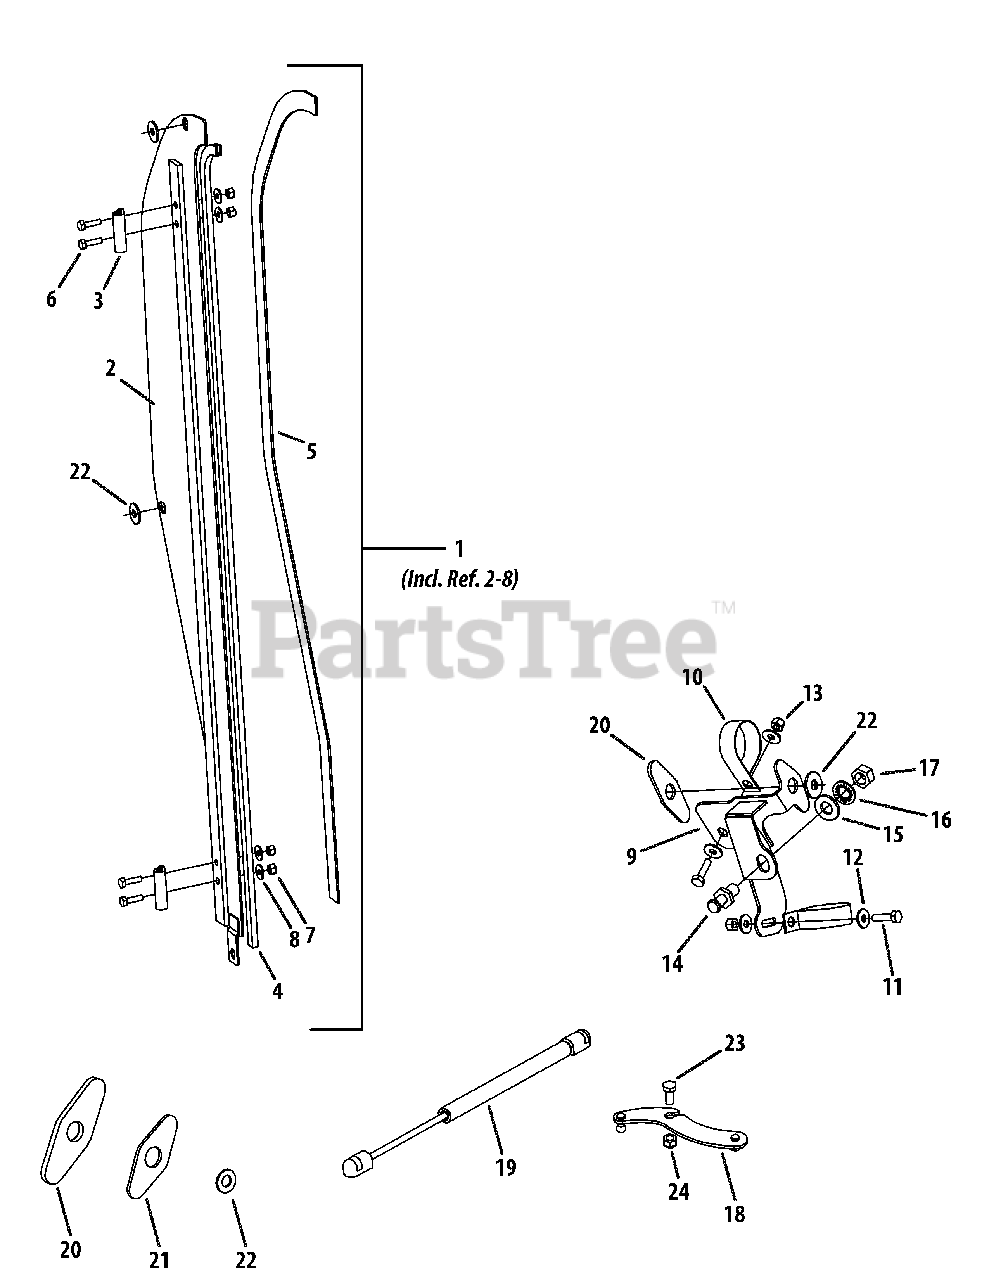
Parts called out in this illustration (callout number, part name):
1	Door Hng. Panel-R, (incl. Ref. 2-8)
2	Hinge Panel
3	Tube Frame Hinge, 10 Gauge
4	Standard Trim Lock, 1/8" Grip
5	Foam Seal, 1" X 1/8
6	Hex Bolt, 1/4-20 x 1"
7	Washer, 1/4"
8	Lock Nut, 1/4-20
9	Door Striker - R
10	Door Hardware Kit
11	Hex Bolt, 1/4-20 x 1"
12	Washer, 1/4"
13	Lock Nut, 1/4-20
14	Striker Bolt For Rotary Latch
15	Washer, 1/2"
16	Lock Washer, 1/2"
17	M10 Nut
18	Door Frame Spring Mount, RH
19	Gas Spring (12") W/Quick Release
20	Rubber Door Filler, ROPS
21	S/M 2.75 X 1.25 Door Washer
22	Washer, 3/8"
23	Hex Bolt, 5/16-18 x 3/4"
24	Locknut, 5/16-18
